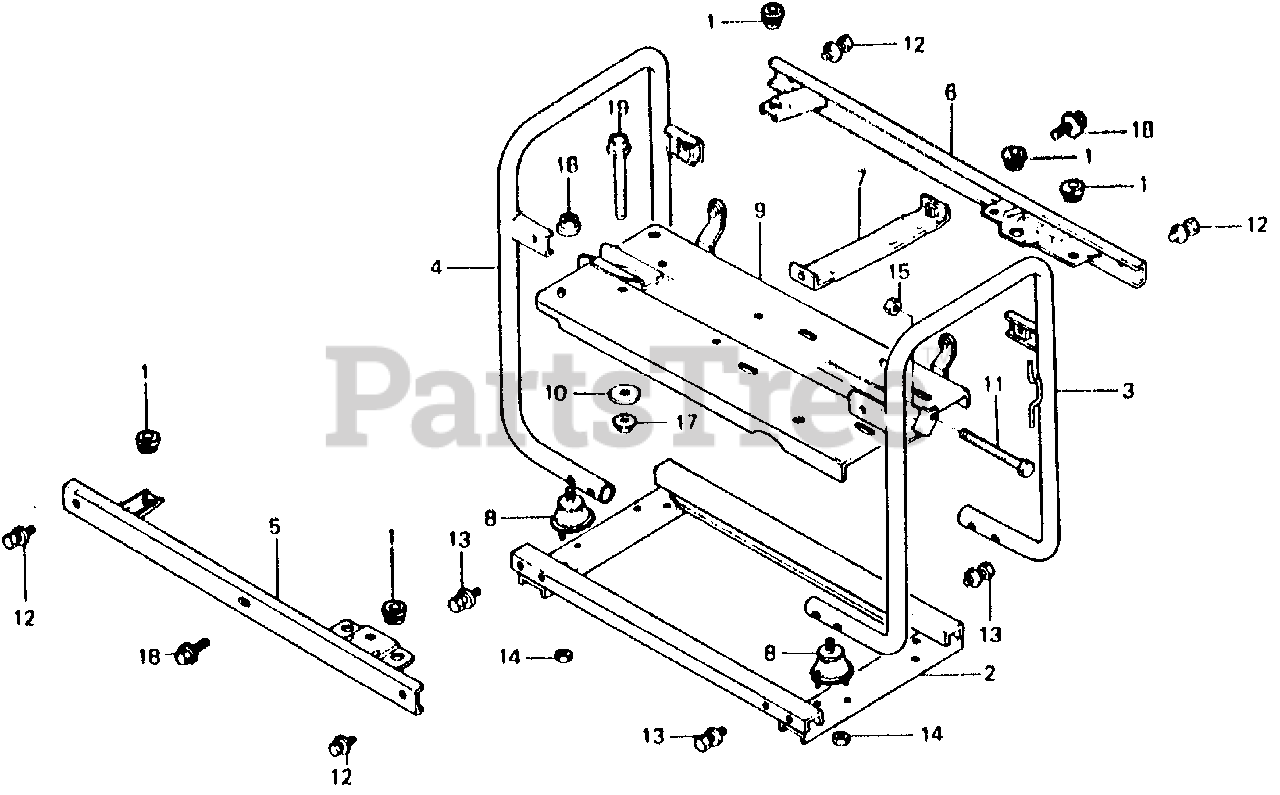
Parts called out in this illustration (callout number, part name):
1	RUBBER, TANK CUSHION
2	BED, FRAME
3	FRAME, R. SIDE
4	FRAME, L. SIDE
5	FRAME, FR. (UPPER)
6	FRAME, RR. (UPPER)
7	STOPPER, ENGINE (NOT AVAILABLE)
8	RUBBER, ENGINE SETTING
9	BED, ENGINE
10	WASHER, EX. MANIFOLD
11	BOLT, HEX. (8X65) (NOT AVAILABLE)
12	BOLT-WASHER (8X16)
13	BOLT-WASHER (8X20)
14	NUT, HEX. (6MM)
15	NUT, HEX. (8MM)
16	NUT, FLANGE (8MM)
17	NUT, FLANGE (10MM)
18	BOLT, FLANGE (6X12)
19	BOLT, FLANGE (10X50)
